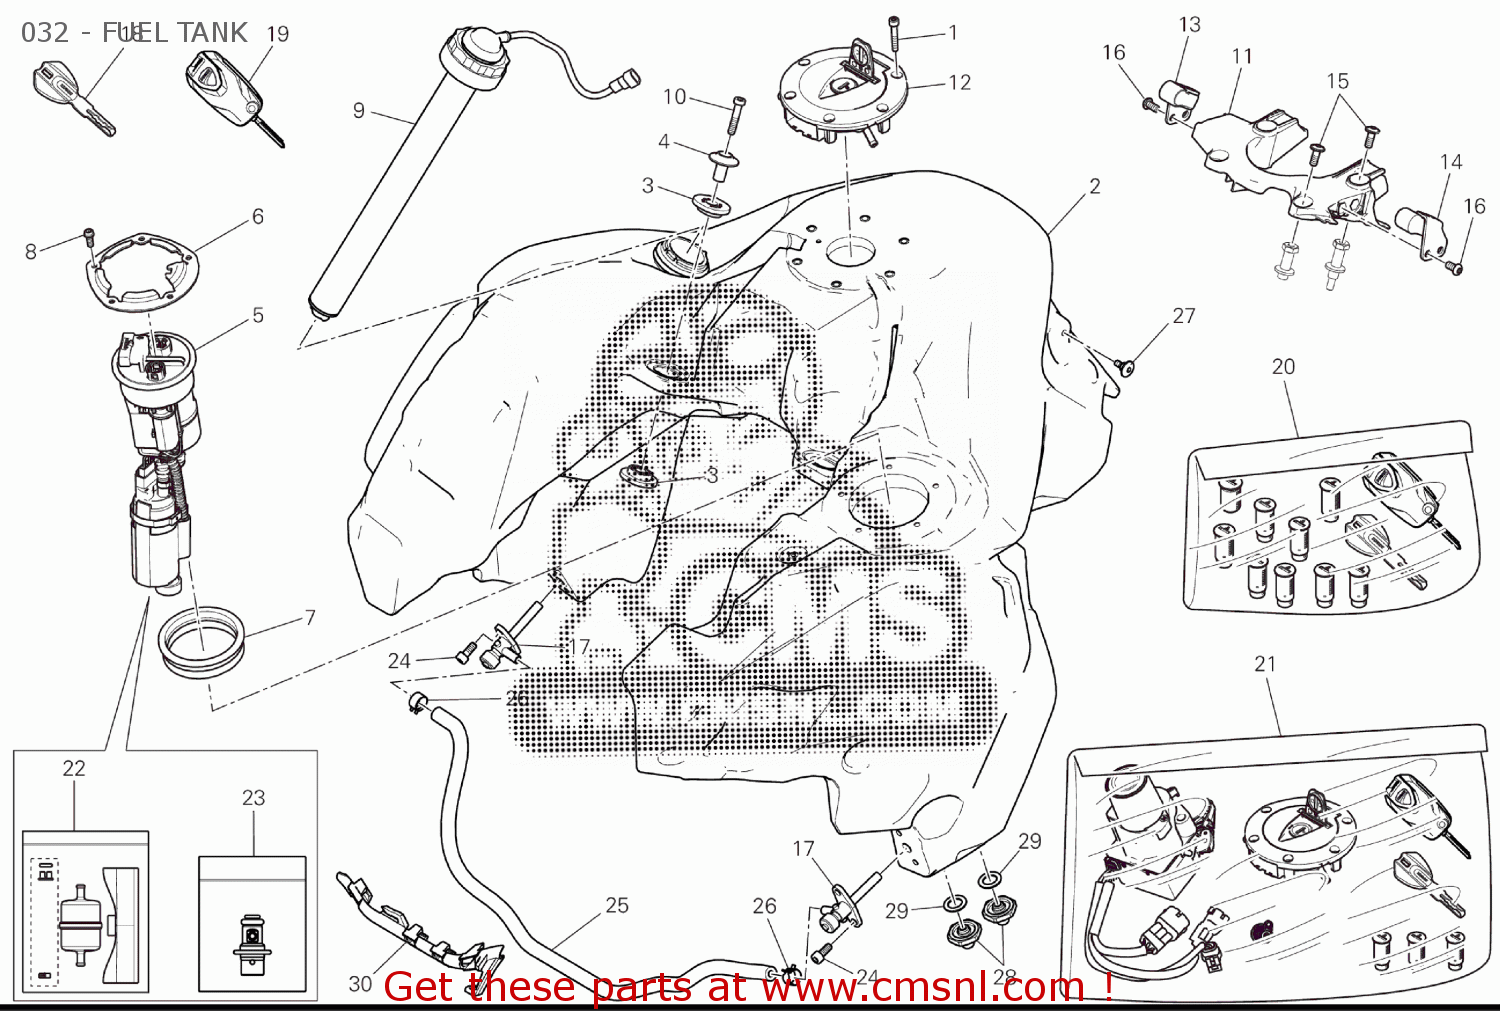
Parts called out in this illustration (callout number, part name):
1	SCREW TCEI M5X30
2	FUEL TANK
3	PAD
4	SPACER
5	FUEL PUMP
6	BRACKET, FUEL PUMP
7	GASKET
8	SCREW TCEI M5X10
9	FUEL LEVEL GAUGE
10	SCREW TCEIF M6X35
11	BRACKET, FUEL TANK REAR
12	CAP SET, FUEL TANK
13	RIGHT PLATE
14	LEFT PLATE
15	SCREW
16	SCREW
17	FUEL COCK
18	KEY WITH TRANSPONDER PASSIVE
19	KEY WITH TRANSPONDER ACTIVE
20	ROTORS AND KEY KIT
21	HANDS FREE 868 MHZ KIT
24	SCREW TCEI M6X14
25	PIPE
26	SPRING,COIL,BLACK
27	SCREW TBEI M5X13.5
28	NUT, SPECIAL
29	O-RING
30	HOLDER
